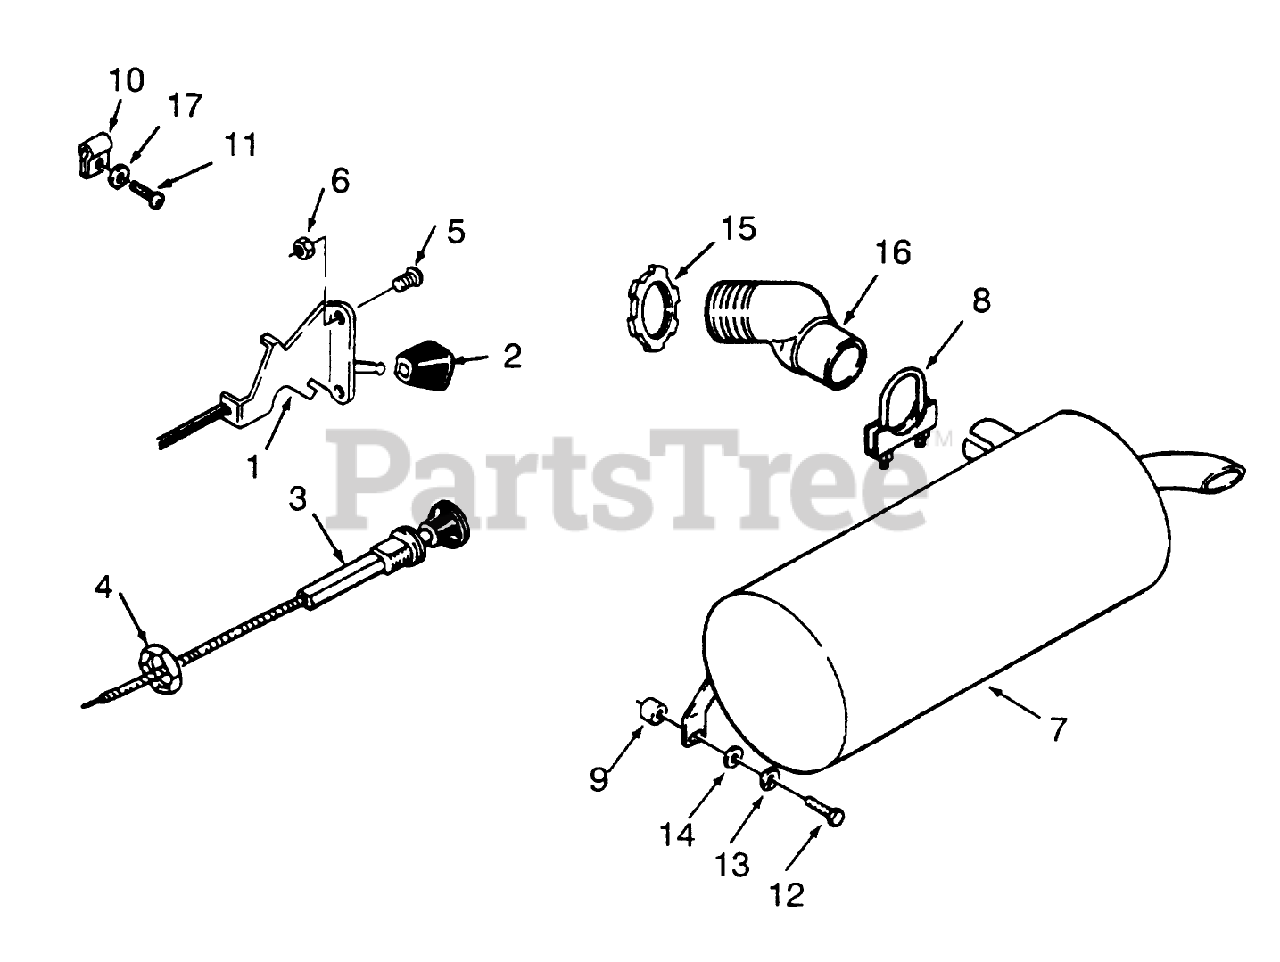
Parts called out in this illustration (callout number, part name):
1	CONTROL-THROTTLE
3	CONTROL CHOKE
4	NUT-HEX PALNUT
9	SPACER
10	KOHLER 48-154-01
11	KOHLER X-67-83
12	SCREW-HH
13	WASHER-LOCK
14	WASHER-FLAT
15	KOHLER AC-1536
16	KOHLER47-054-01
17	KOHLER X-25-72
